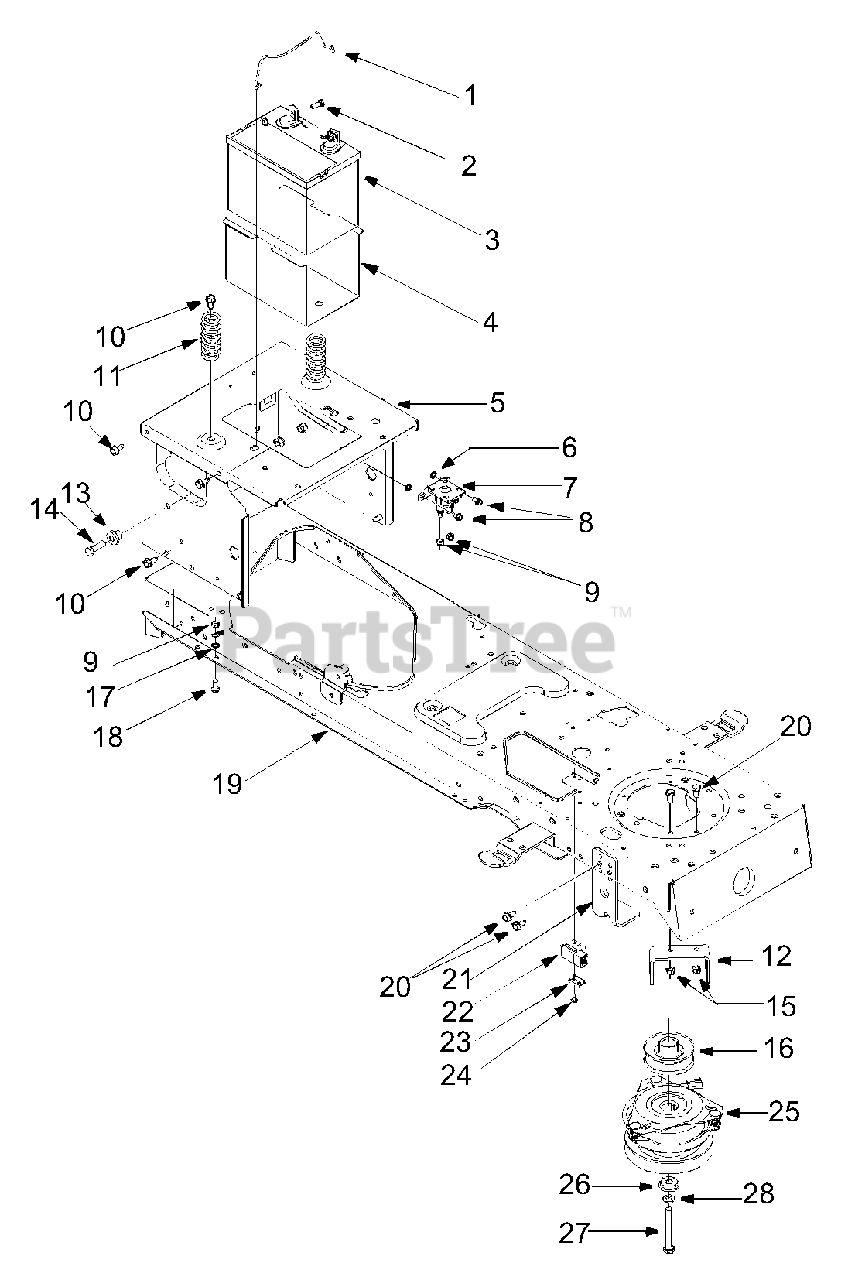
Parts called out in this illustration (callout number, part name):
1	Battery Hold-Down Rod
2	Hex Cap Screw 1/4-20 x 0.62
3	Battery, 270 CCA
7	Solenoid 12 v., 100 amp.
8	TT Screw 1/4-20 x 0.5
9	Hex Lock Nut 1/4-20
10	AB Screw 5/16-12 x 0.75
11	Compression Spring
14	Hex Bolt 3/8-16 x 1.25
15	Hex Lock Nut
16	Pulley: Single Speed
17	Shoulder Screw
18	TT Screw 1/4-20 x 0.75
20	Hex Bolt 5/16-18 x 0.625
22	Switch
23	Switch Plate
24	Screw #10-16 x 0.5
25	Clutch: Electric PTO
26	Shoulder Spacer
27	Hex Bolt 7/16-20 x 3.25
